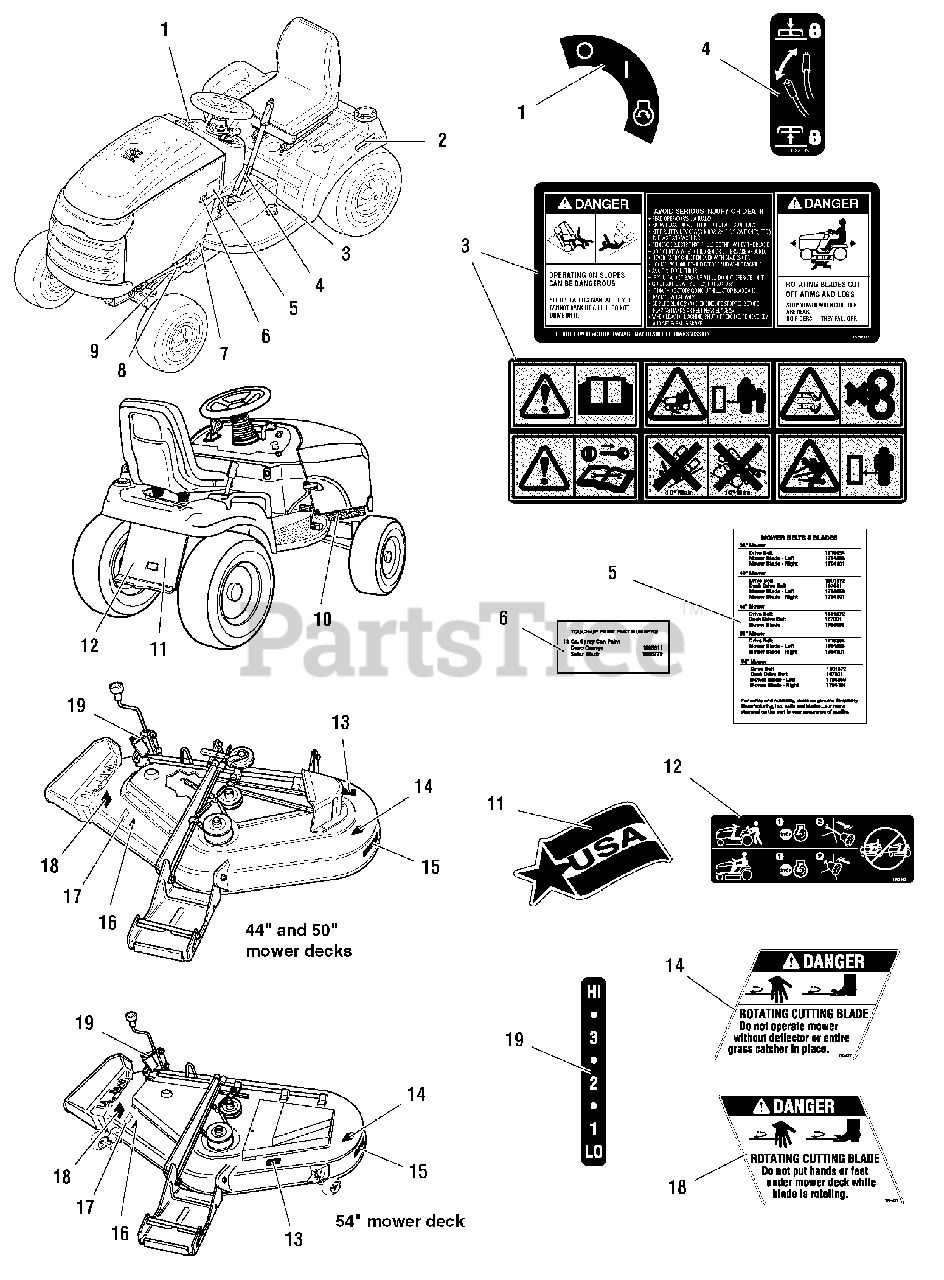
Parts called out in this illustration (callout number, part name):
1	DECAL, Ignition Switch Symbols, White/Black
2	DECAL, Automatic Control Traction
3	DECAL, Tunnel Cover, Danger Slopes/Blades
3	DECAL, Tunnel Cover, Danger Slopes/Blades, (Export)
3	DECAL, Tunnel Cover
4	DECAL, Lift Lever Symbols
5	DECAL, Drive Belts, Mower Blades (38 Tooth Sprocket Mower)
5	DECAL, Drive Belts, Mower Blades
6	DECAL, Touch Up Paint, Deep Orange
6	DECAL, Touch-Up Paint, Red
7	DECAL, Protective Sticker
8	LABEL, Decibel, Power Massv
9	DECAL, I.D. Plate
10	DECAL, Patent
11	DECAL, USA Logo Stars & Stripe
12	DECAL, Transmission Release Valve
13	DECAL, I.D. Plate
14	DECAL, Danger Do Not Put Hands/Feet in Mower
15	DECAL, Free Floating Mower, Silver
16	DECAL, OPEI Certified
17	DECAL, 44", Silver on Black with Stripe
17	DECAL, 50", Silver on Black with Stripe
17	DECAL, 52" Deck
17	DECAL, 54", Silver on Black with Stripe
18	DECAL, Danger Do Not Operate without Deflector
19	DECAL, Height of Cut
